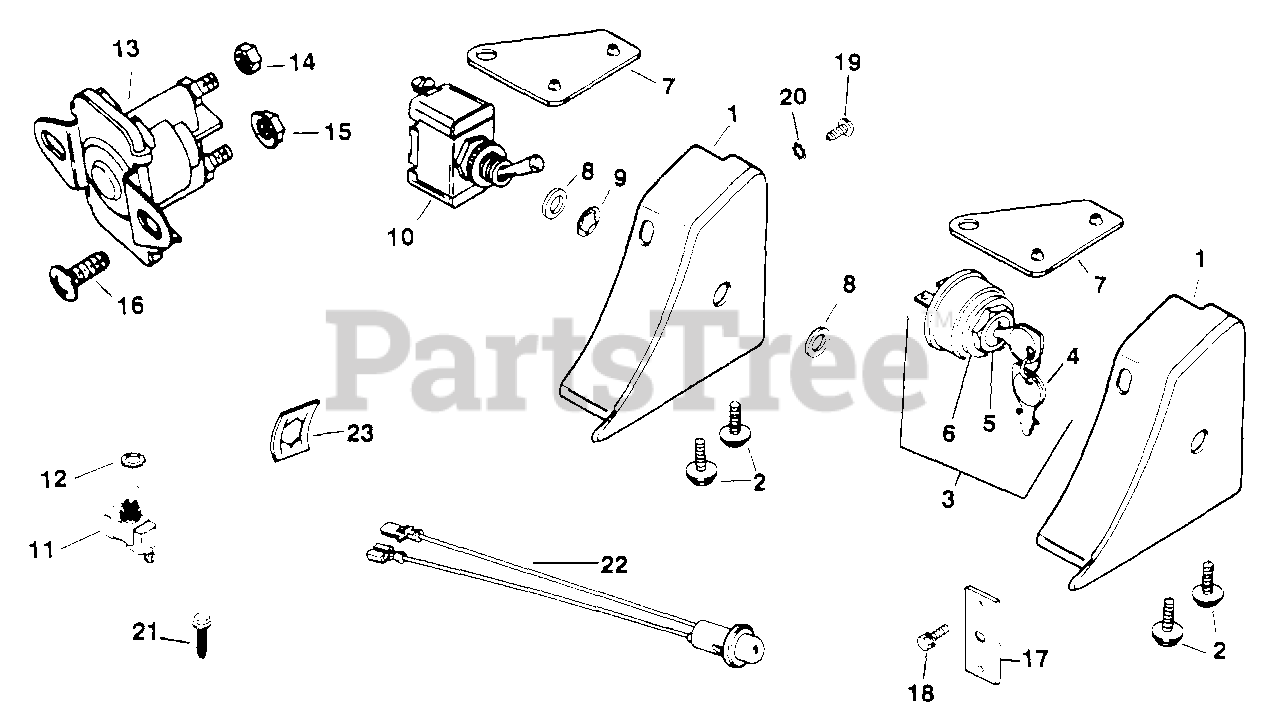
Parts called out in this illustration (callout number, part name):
3	SWITCH ASSY, KEY (KM)-USE 25 099 32-S
4	KEY, SET -USE 48 340 01-S
5	NUT, KEY SWITCH
6	WASHER, INTERNAL TOOTH
13	SOLENOID - WATERPROOF (KM)-USE 25 435 08
19	SCREW, WSH HD TAP 1/4-20-5/8" - DISCONTINUED
20	WASHER,INT EXT TOOTH LOCK 1/4"
